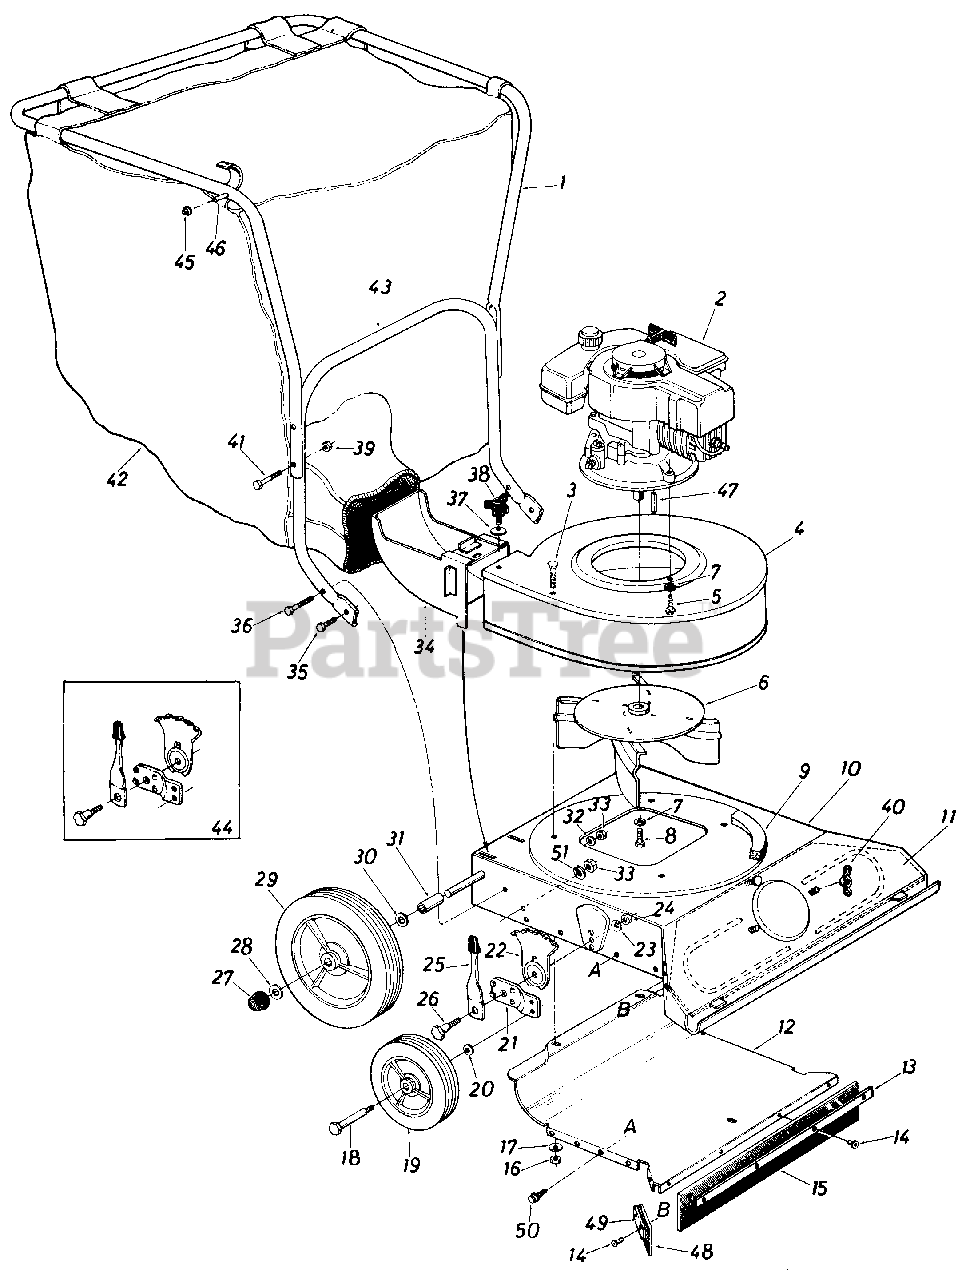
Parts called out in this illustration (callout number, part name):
1	Upper Handle (Painted)
2	Engine
3	Carriage Bolt 5/16-18 x .62" Lg.*
4	Blower Housing Ass'y.
5	Hex Tap Scr. 3/8-16 x 1.00" Lg.
6	Impeller Ass'y.
7	L.Wash. 3/8" I.D.*
8	Hex Bolt 3/8-24 x 1.0" Lg. w/Patch
9	P.V.C. Foam Strip (4-Pcs. 12" Lg.)
10	Vacuum Deck Ass'y.
11	Front Baffle Ass'y.
12	Lower Baffle Ass'y.
13	Wiper Retaining Strip
14	Pop Rivet.188" Dia.
15	Nozzle Wiper Rear
16	Hex Nut 5/16-18 Thd.*
17	Bell.Wash. .34" I.D. x .87" O.D.
18	Shld. Bolt 1/2" Dia. x 1.45" Lg. (3/8-16)
19	Wheel Ass'y. Comp. 8 x 1.75" - Front
20	Bell.Wash. .39" I.D. x 1.12" 0. D.
21	Wheel Pivot Bar
22	Index Plate
23	Bell.Wash. .39" I.D. x 1.12" 0. D.
24	Hex Nut 3/8-16Thd.*
25	Spring Lever Ass'y. w/Knob
26	Shoulder Bolt .500" x 7/16" Lg. (3/8-16)
27	Push Cap .50" Rod (Black)
28	Fl -Wash 1/2" I.D. x 1.0" O.D. x .06
29	Wheel Ass'y. Comp. 1.0 x 1.75" R ear
30	Fl.Wash. 1/2" I.D. x 1.0" O.D. x .06
31	Wheel Spacer 1/2" I.D. x 15/16" Lg.
32	Bell,-Wash. .39" I.D. x 1.12" O . D.
33	Hex Nut 3/8-16 Thd.*
34	Air Duct Ass'y.
35	Hex Bolt 3/8-16 x .75" Lg.*
36	Hex Bolt 3/8-16 x 1.50" Lg.*
37	Bel I .Wash. .34".1. D. x .87 " O. D .
38	Thumb Scr. 5/16-18 x .75" Lg.
39	Hex Cent. L.Nut 1/4-20Thd.
40	Wing Nut 1/4-20 (Plastic)
41	Hex Bolt 1/4-20 x 1.75" Lg.
42	Vacuum Bag (6.6 Bushel)
43	Lower Handle (Painted)
44	Height AdjusterAss'y. Comp. -R.H.
45	Push Speed Nut .25" Dia.
46	Stud Pin .250" Dia. x 1.75" Lg.
47	Sq. Key 3/16 x 3/16 x 1.00"Lg.
48	Nozzle Wiper Side
49	Wiper Retaining Strip
50	HexWash. Hd. "F" TapScr. # 1 0
51	L-Wash. 3/8" 1.[;) .*
